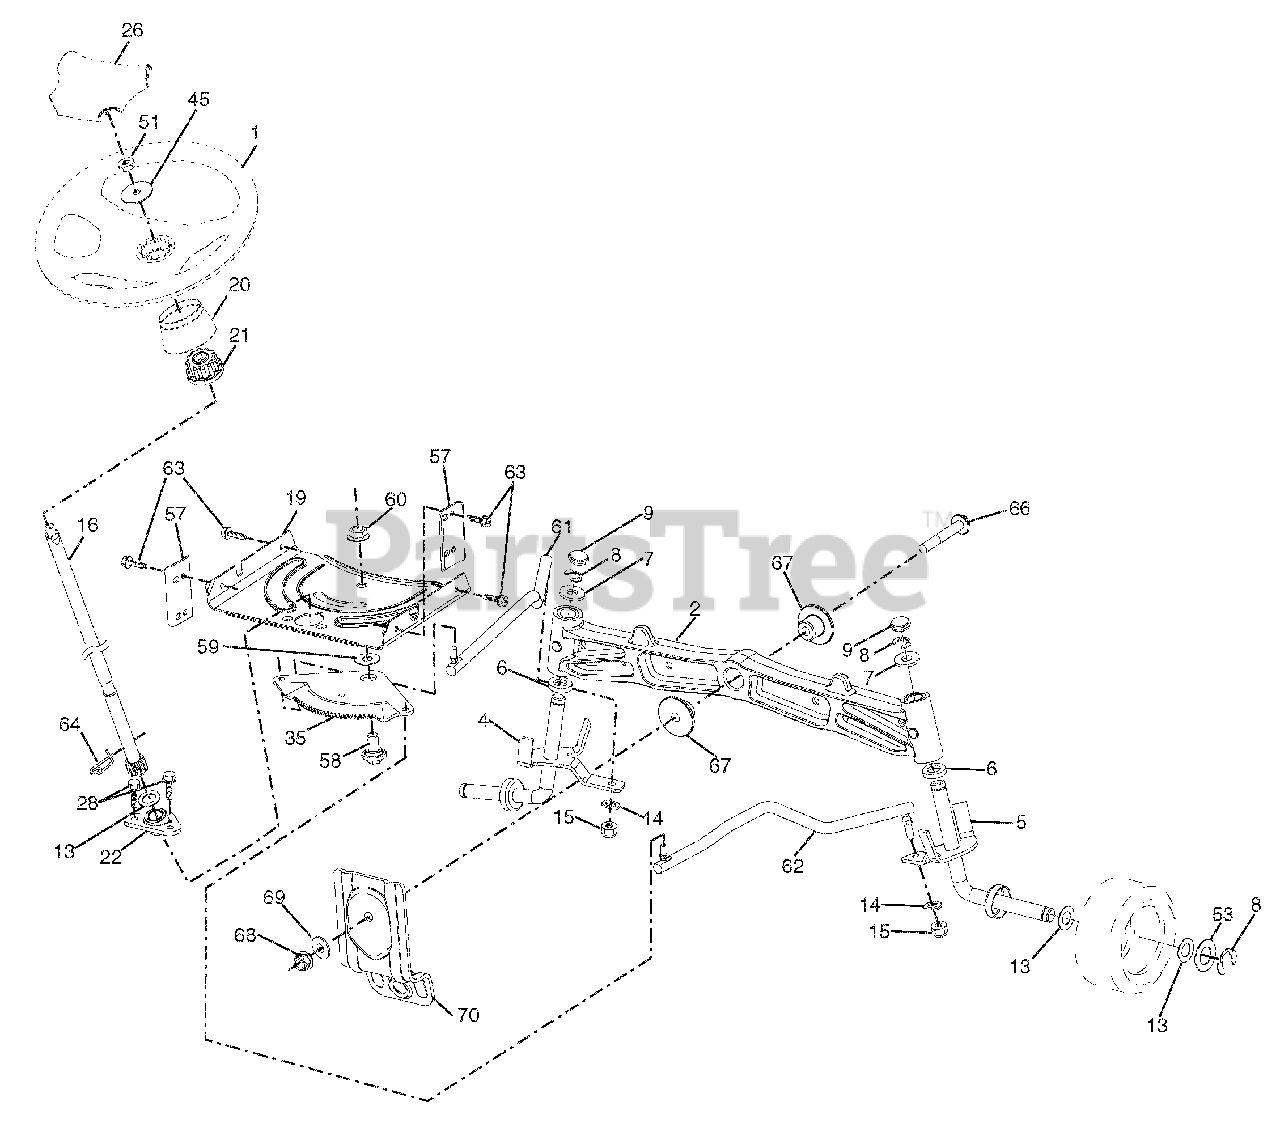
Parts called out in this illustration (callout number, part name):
1	WHEEL STEERING
2	AXLE.CAST IRON
4	SPINDLE.WELDED.LH.15"TEX
5	SPINDLE.WELDED.RH.15"TEX
6	WASHER.THRUST..75 X 1.230
7	WASHER.25/32 X 1-5/8 X 16GA.
8	RING.KLIP.#T5304-75
9	CAP.SPINDLE.FR.TOP.BLK.
13	WASHER.25/32 X 1 1/4 X 16 GA.
14	Washer, Lock 3/8
15	NUT.CROWNLOCK.3/8-24
16	SHAFT.STEER.3/4 TEX.NON-PLATED
19	PLATE.STEER.DDL.NLT/NGT
20	BOOT.STEERING.TEX ELITE.428
21	ADAPTER.WHEEL.STRG..760
22	STEERING SUPT.LOWER
26	CAP.WHL.STRG.HRS/SRS.BLACK
28	SCREW.HEXWSH THDR3/8-16X3/4.BL
35	GEAR SECTOR.PLATE.DDL.NLT/NGT
45	WASHER.9/16ID X 2-3/8OD.12GZIN
51	NUT.HEX.JAM.TOPLOCK.1/2-20 UNF
53	WASHER.HARDEN..793 X 1.637X060
57	BRACKET.UPSTOP.TEX
58	BOLT.SHOULDER.SECTOR.PIVOT.CFM
59	WASHER.THRUST.SECTOR.STEER.NLT
60	NUT.FLANGE LOCK.5/8-11
61	DRAGLINK.LH.BALLSTUD.DDL.
62	DRAGLINK.RH.BALLSTUD.DDL
63	SCREW.5/16-18X3/4.SMGML.TAP/BL
64	RETAINER.CLIP.SPRING.STEERING
66	BOLT.HEX.FGHD.7/16-14 X 3.SERR
67	BUSHING.PM.FRONT AXLE
68	NUT.LOCK.FLANGE.7/16-14.GR5
69	WASHER.1.5 X .505 X .118
70	BRACKET.DECK.SUSPENSION.FRONT
